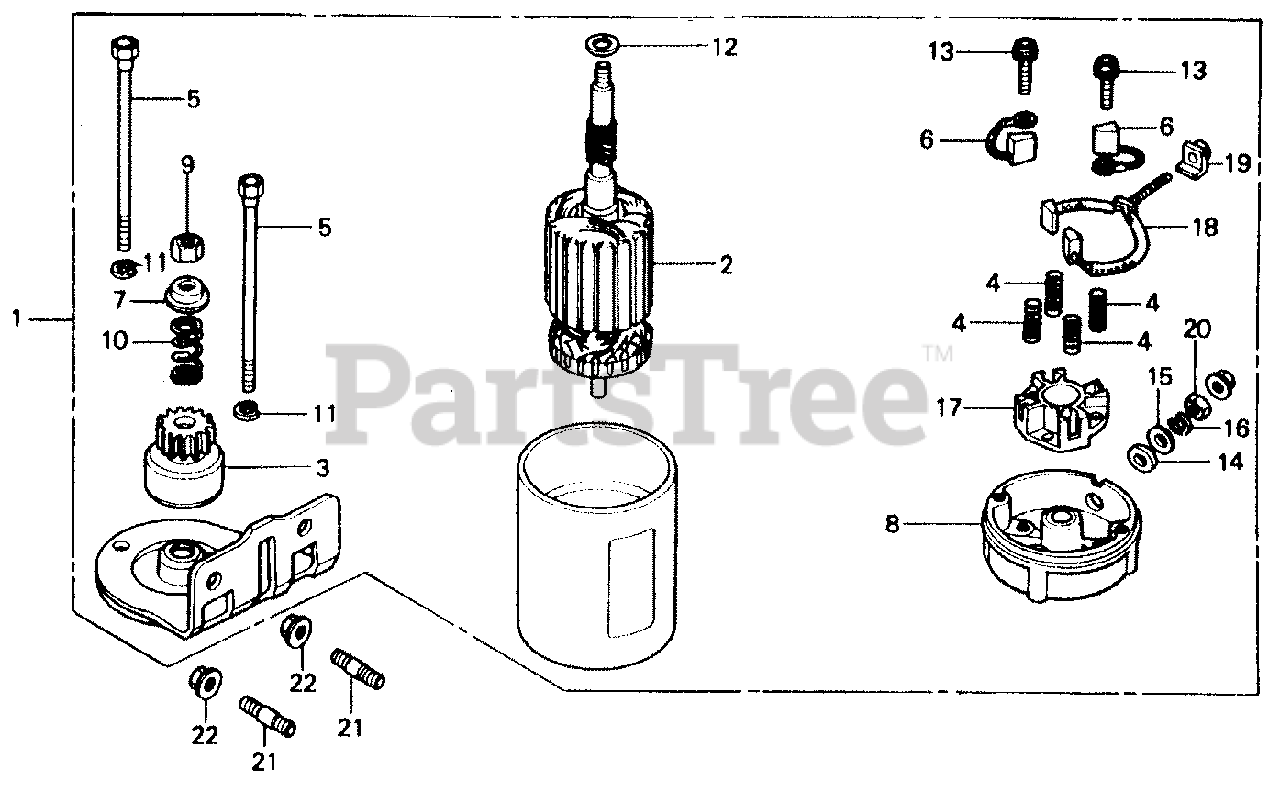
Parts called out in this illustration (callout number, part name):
1	MOTOR ASSY., STARTER (N/A - SEE PIB# 91-0020) (NOT AVAILABLE)
2	ARMATURE
3	GEAR, PINION
4	BRUSH, SPRING
5	BOLT, THROUGH
6	BRUSH, SPRING
7	SPACER (NOT AVAILABLE)
8	COVER, RR.
9	NUT, STOP (NOT AVAILABLE)
10	SPRING, ANTI-DRIFT (NOT AVAILABLE)
11	WASHER, LOCK
12	WASHER
13	BOLT-WASHER (NOT AVAILABLE)
14	WASHER, INSULATION (NOT AVAILABLE)
15	WASHER B (NOT AVAILABLE)
16	WASHER B, LOCK (NOT AVAILABLE)
17	HOLDER, BRUSH
18	BRUSH, SPRING
19	BUSHING
20	NUT
21	BOLT, STUD (8X30)
22	NUT, FLANGE (8MM)
